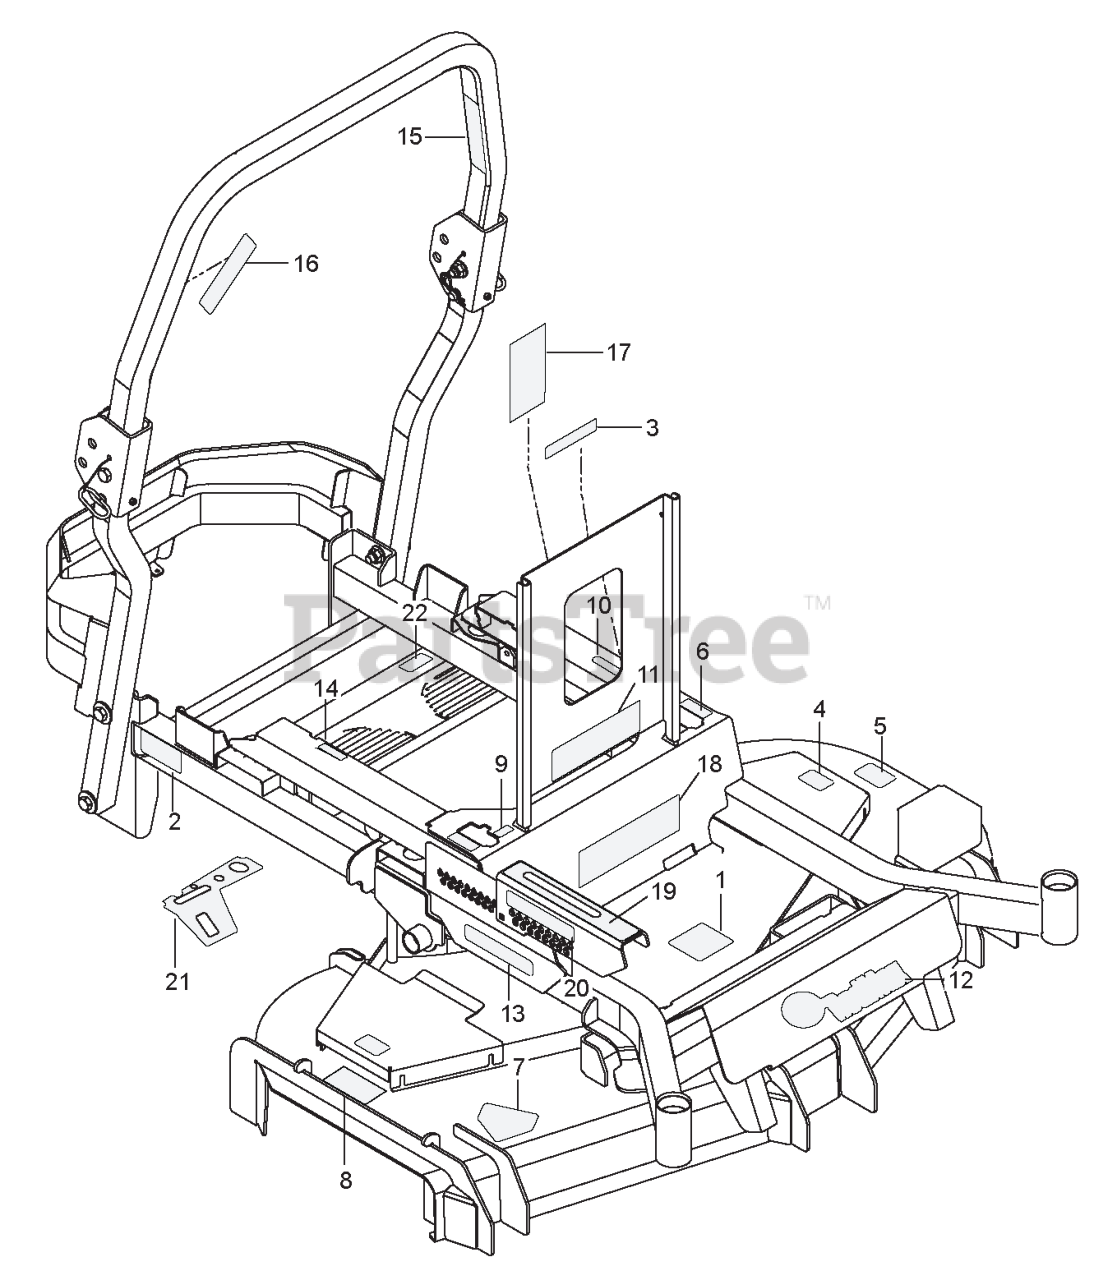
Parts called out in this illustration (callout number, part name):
1	DECAL, 72" BELT ROUTING
2	DECAL, BELT DRIVE
3	EURO DECAL-BATTERY WARNIN6
4	DECAL.DECK.6MIL.EURO.NOSTEP
5	DECAL DECK DECAL DECAL.DECK.72
6	DECAL.ZTR.MTNCONTROL.2015.PPRO
7	DECAL, DECK DEFLECTOR, WARNING
8	DECAL.DECK.6MIL./DEF.SHLD.WARN
9	DECAL.ZTR.TRACKING.GRAPHIC
10	DECAL.ZTR.TRACKING.GRAPHIC
11	DECAL ZTR WARNING DECAL DECAL.
12	DECAL ZTR BRAND GRAPHIC DECAL.
13	DECAL ZTR SIDE RAIL GRAPHIC DE
14	DECAL ZTR INSTRUCTION GRAPHIC
15	DECAL ROPS DECAL DECAL.ROPS.PZ
16	DECAL, ROPS, WARNING
17	DECAL, SERVICE
18	DECAL ZTR MODEL NUMBER DECAL.Z
19	DECAL ZTR INSTRUCTION GRAPHIC
20	DECAL ZTR INSTRUCTION GRAPHIC
21	DECAL ZTR CONTROL PANEL DECAL.
22	DECAL ZTR INSTRUCTION GRAPHIC
